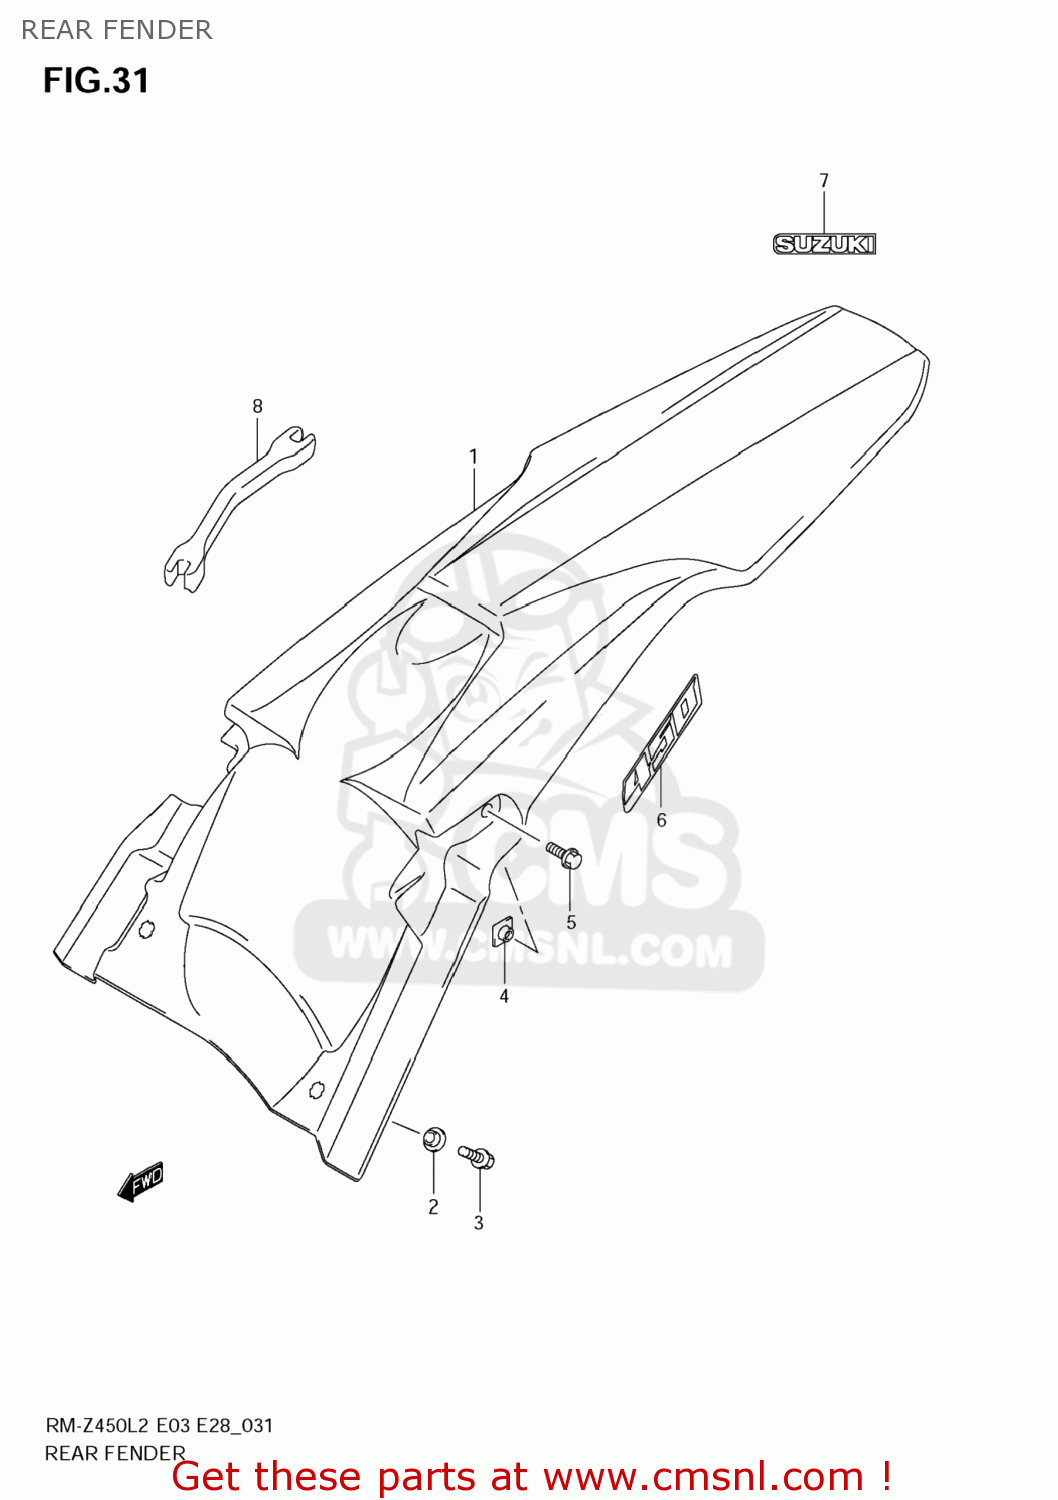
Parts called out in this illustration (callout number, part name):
1	FENDER,RR
2	WASHER,FR FENDER
3	BOLT
4	NUT,RR REFLECTOR
5	BOLT
6	EMBLEM,RR FENDER
7	EMBLEM,SUZUKI
8	OPEN SPANNER(6.4X6.8)
